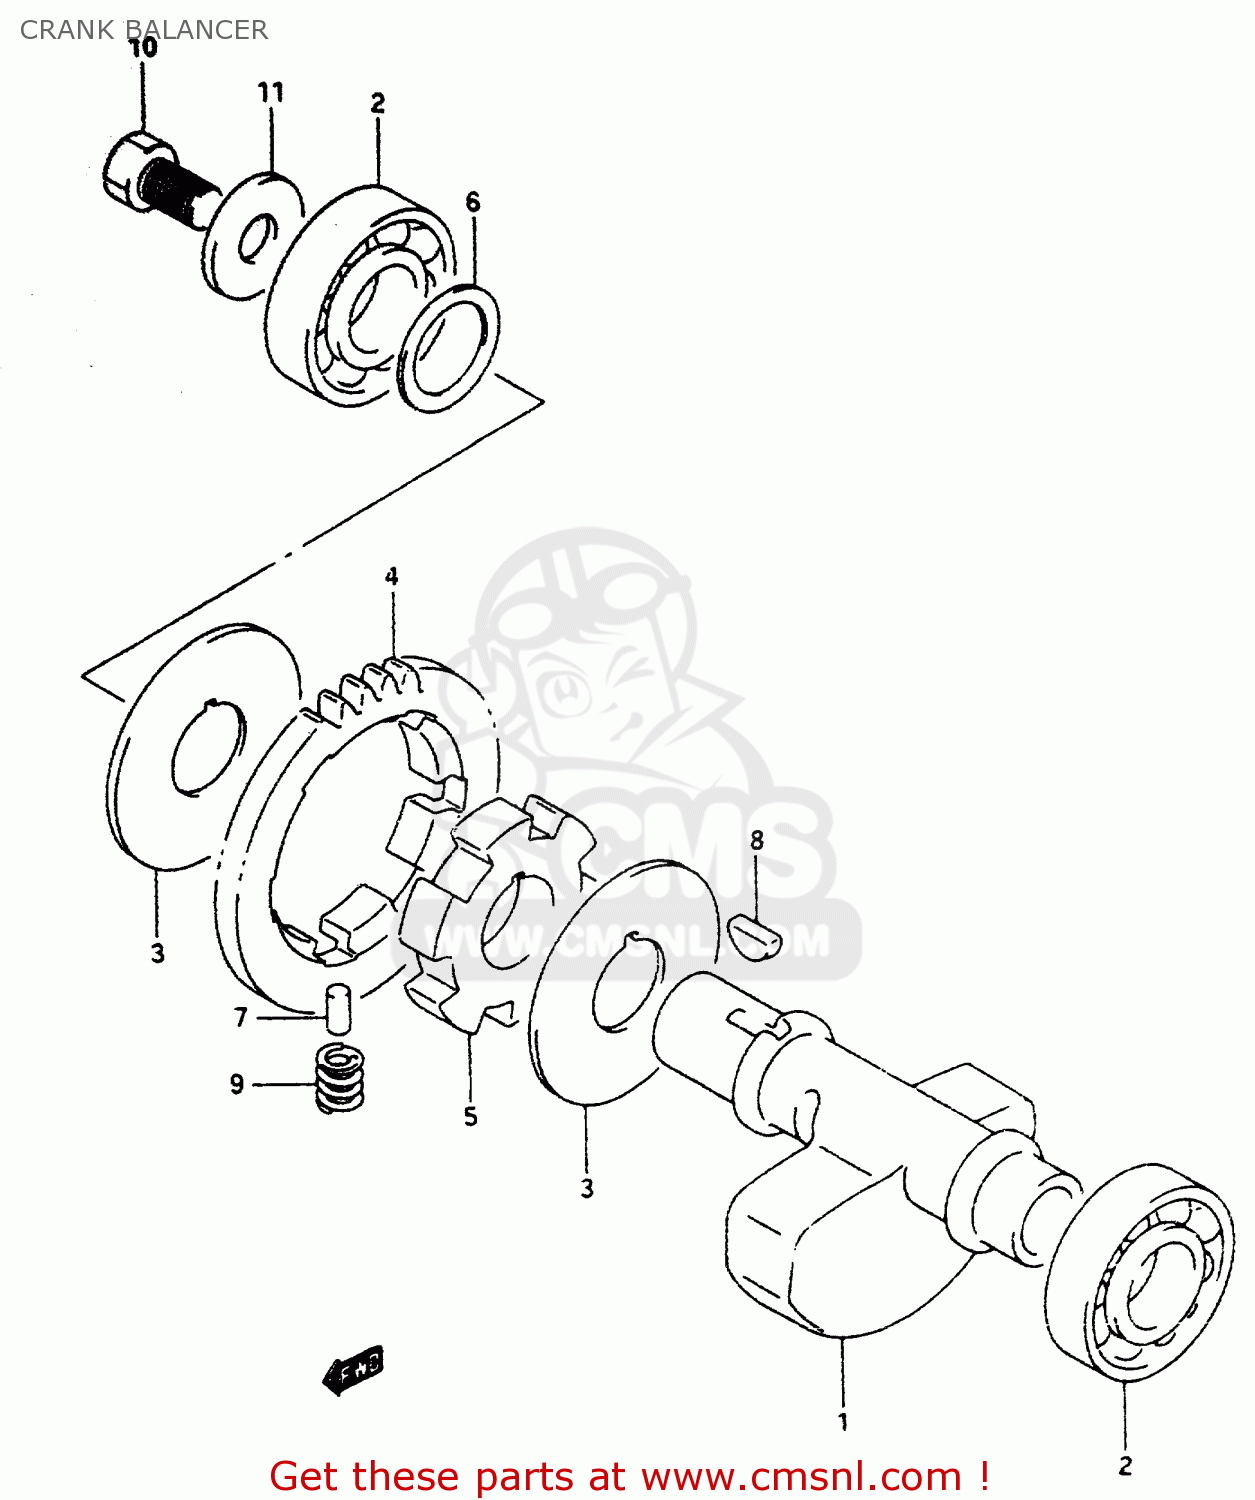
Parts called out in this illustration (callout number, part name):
1	SHAFT,CRANK BALANCER
2	BEARING(20X47X14)
3	WASHER
4	GEAR,CRANK BAL DRIVEN(NT:37)
5	RACE,CRANK BALANCER DRIVEN GEAR
6	SHIM(20X28X0.5)
7	PIN(4.5X9.5)
8	KEY
9	SPRING
10	BOLT
11	WASHER
